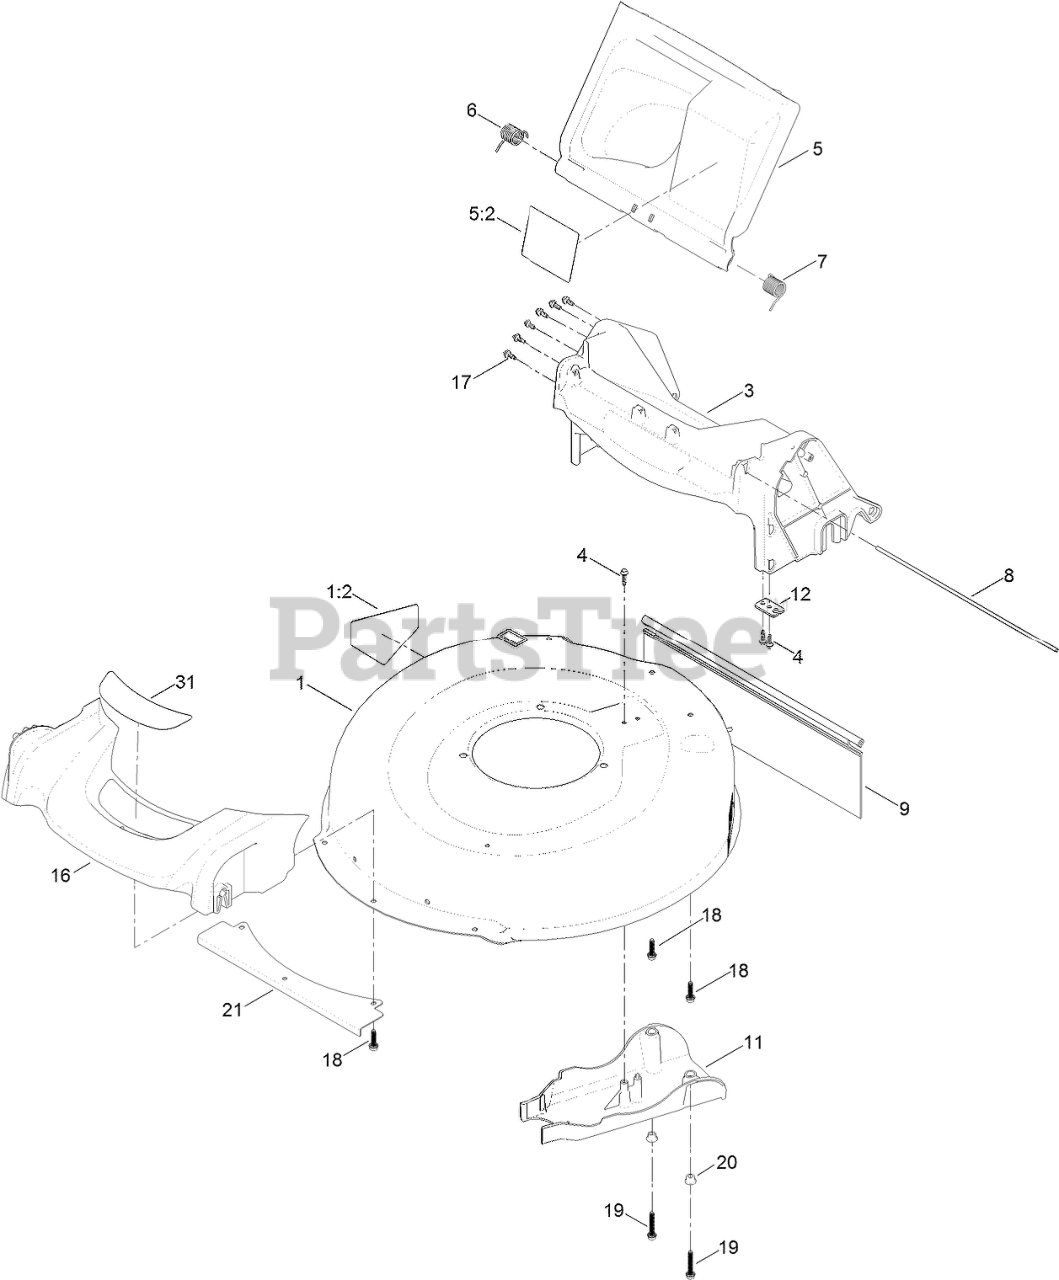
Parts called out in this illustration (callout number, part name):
1	HOUSING ASM
1:2	DECAL-DANGER
3	CHUTE ASM
4	SCREW-HWH
5	REAR DEFLECTOR ASM
5:2	DECAL-WARNING
6	SPRING-TORSION
7	SPRING-TORSION
8	ROD-DOOR
9	SHIELD-TRAILING
11	COVER-BELT
12	BRACKET-CABLE
16	BUMPER
18	SCREW-FLANGE, PLASTIC
19	SCREW-FLANGE, SERRATED
20	SPACER-FLANGE
21	SHIELD-FRONT
31	DECAL-DECK
